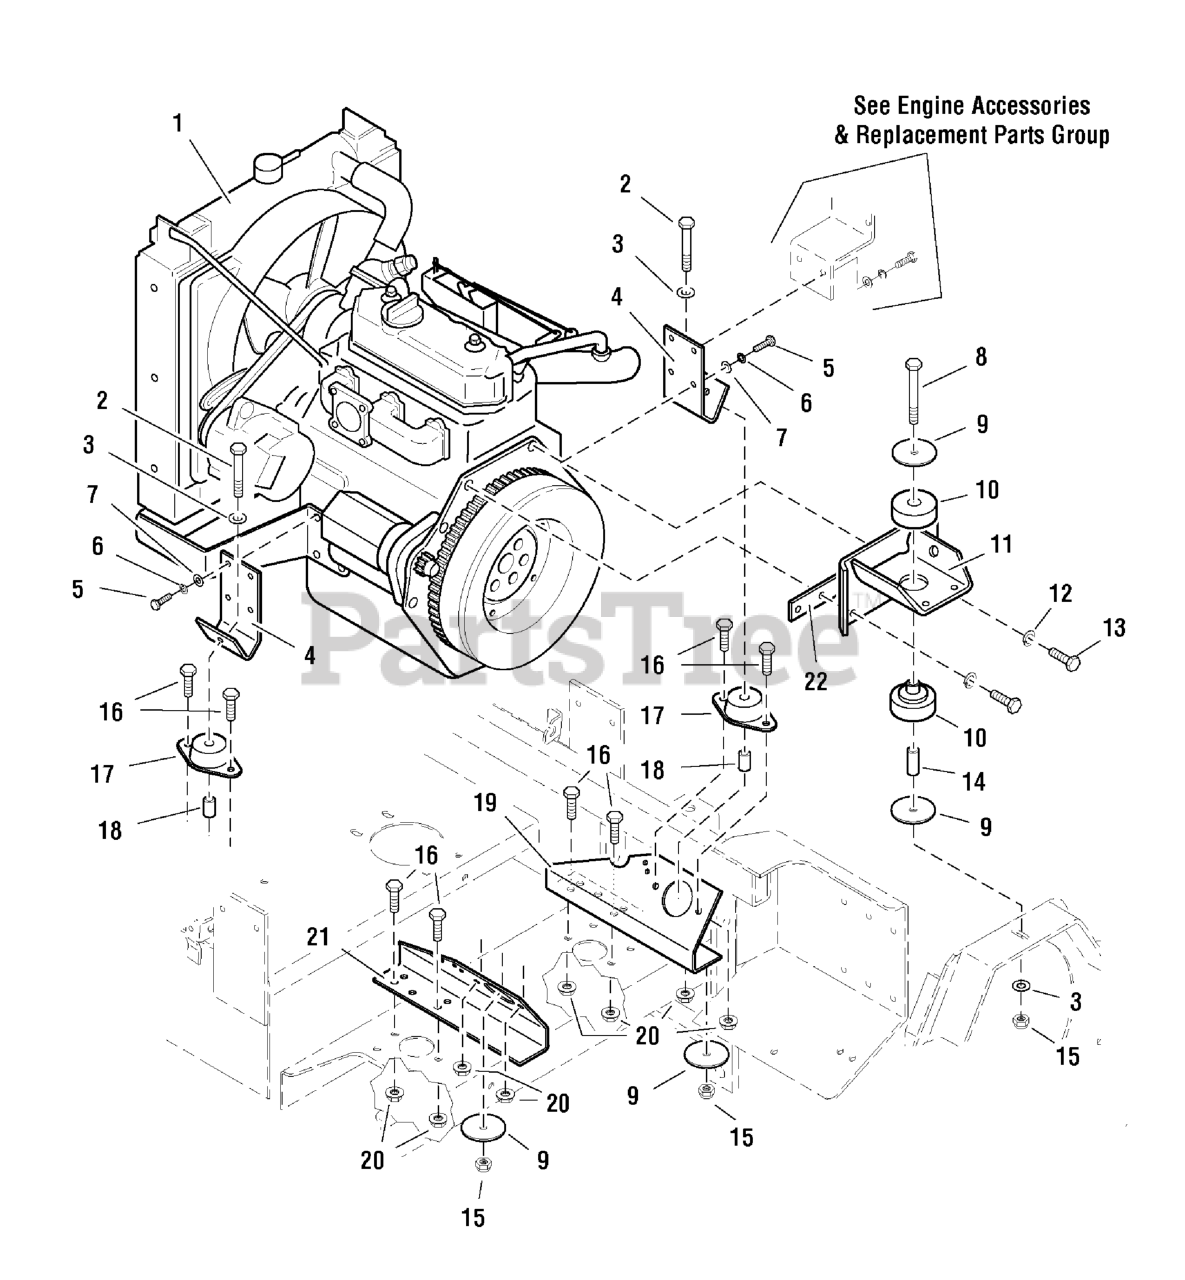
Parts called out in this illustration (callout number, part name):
1	ENGINE, Briggs & Stratton, Diahatsu
2	BOLT, 3/8-16 X 2-1/2" GD5 CZ
3	WASHER, 3/8 SAE
4	MOTOR MOUNT - Front
5	BOLT, M8 x 30MM
6	WASHER, 5/16 LOCK CZ
7	WASHER, 5/16" SAE
8	BOLT, 3/8-16 X 3" GD5 CZ
9	WASHER, 3/8 x 2-1/2
10	ISO MOUNT, Rear (2 piece)
11	MOTOR MOUNT - Upper
12	WASHER, 3/8" Lock
13	BOLT, M10 x 35MM
14	SPACER, .38 x .62 x 1.62
15	NUT, 3/8-16 HEX NYLON LOCK
16	BOLT, 3/8-16 X 1" GD5 CZ
17	ISO MOUNT, Front
18	SPACER, .38 x .50 x 1.00
19	MOTOR MOUNT PLATE - RH
20	NUT, 3/8-16 Hex Serrated Flange
21	MOTOR MOUNT PLATE - LH
22	PLATE, Iso Mount, Rear
